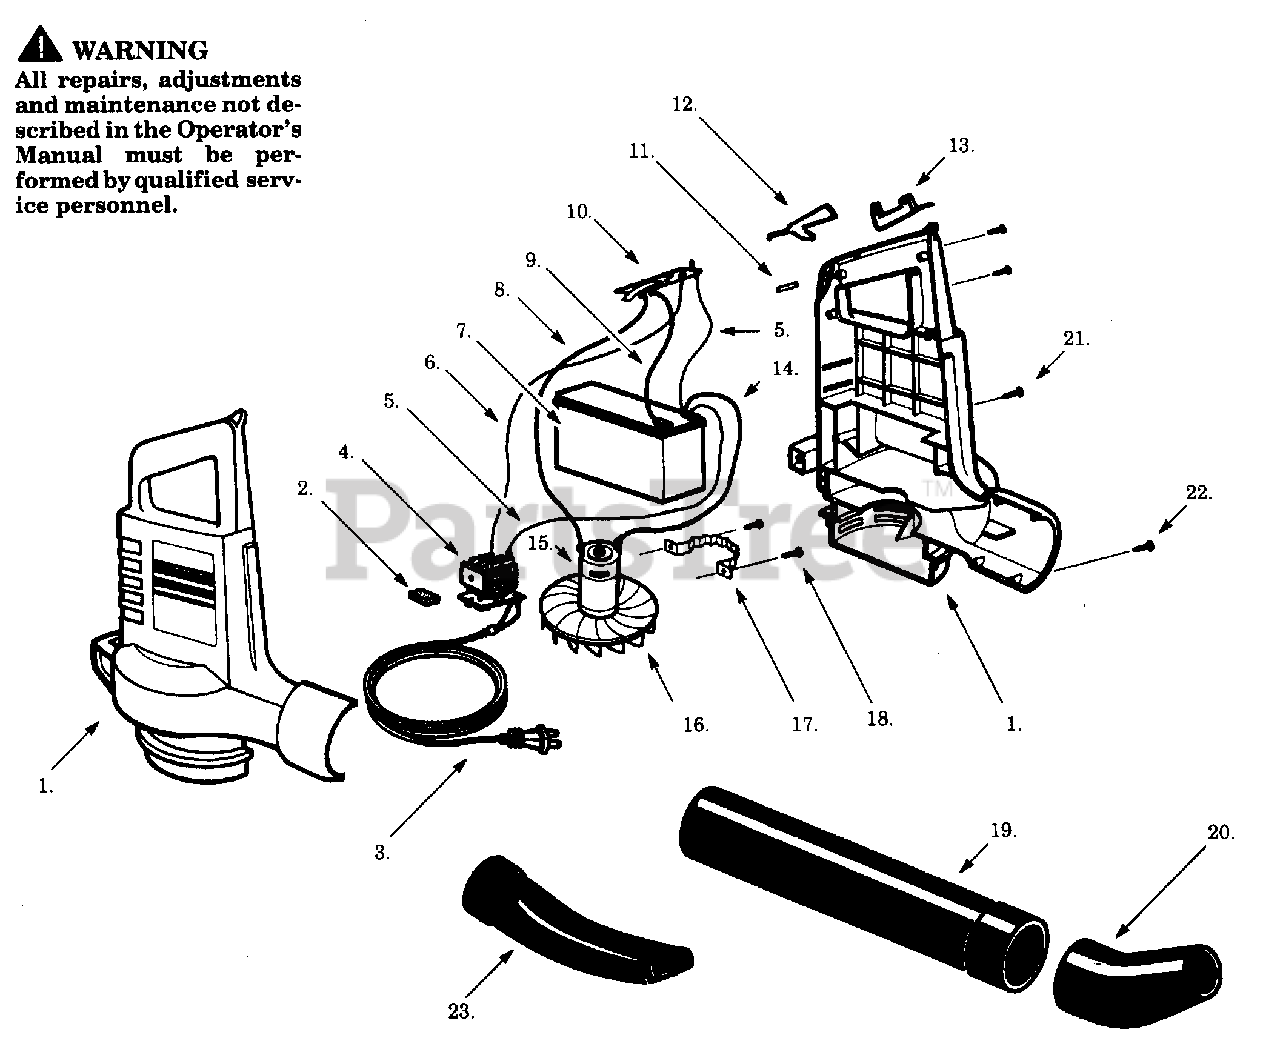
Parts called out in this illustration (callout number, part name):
1	Blower Housing Set
3	Cord Set
5	Leadwire Assy) Black (22 Ga. wire)
6	Leadwire (22 ga) Red
8	Leadwire (14") Red (14 Ga wire)
9	Leadwire (7") White (14 Ga. wire)
10	Circuit Board
11	Roll Pin
12	Trigger Lock
13	Trigger
14	Leadwire (12") Black (14 Ga. wire)
15	Motor Assembly
16	Impeller
17	Motor Clamp
18	Screw (2 required)
19	Outlet Tube
23	Flare Nozzle
